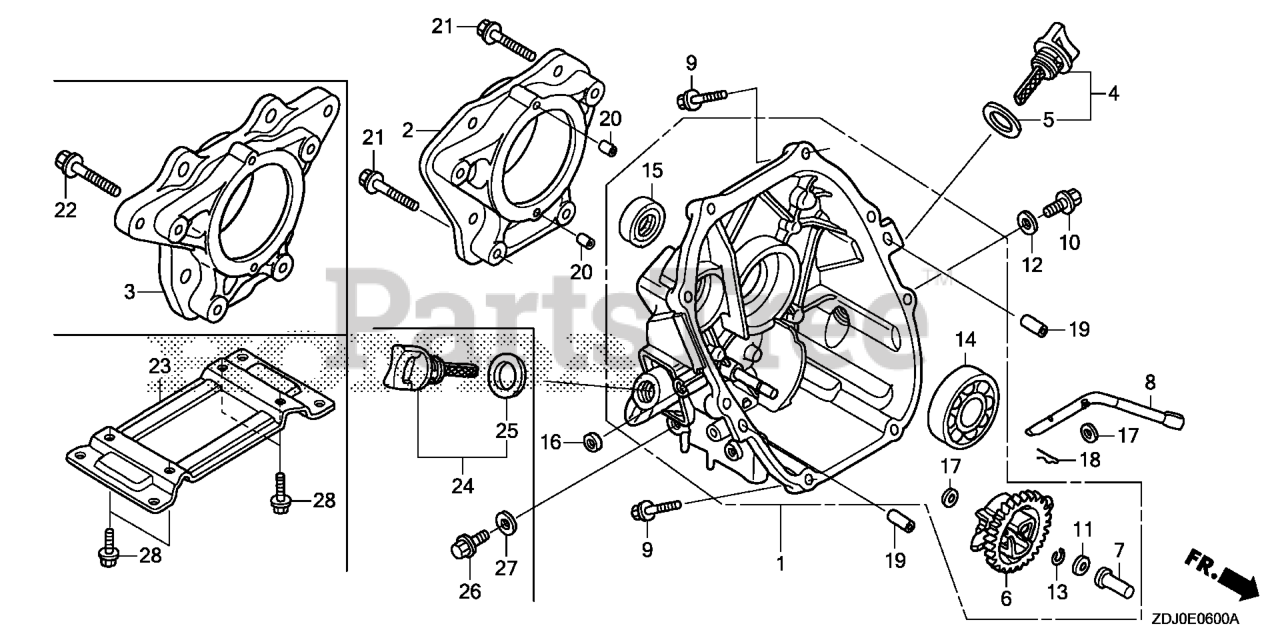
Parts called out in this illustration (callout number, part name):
1	COVER ASSY., CRANKCASE
4	CAP ASSY., OIL FILLER
5	GASKET, OIL FILLER CAP
6	GOVERNOR ASSY.
7	SLIDER, GOVERNOR
8	SHAFT, GOVERNOR ARM
9	BOLT, FLANGE (6X25) Use up to Engine SN 2056819.
10	BOLT, DRAIN PLUG
11	WASHER, THRUST (6MM)
12	WASHER, DRAIN PLUG (10.2MM)
13	CLIP, GOVERNOR HOLDER
14	BEARING, RADIAL BALL (62/22)
15	OIL SEAL (22X41X6)
17	WASHER, PLAIN (6MM)
18	PIN, LOCK (8MM)
19	PIN, DOWEL (8X20)
23	BED, ENGINE
24	CAP ASSY., OIL FILLER
25	GASKET, OIL FILLER CAP
26	BOLT, DRAIN PLUG
27	WASHER, DRAIN PLUG (10.2MM)
28	BOLT, FLANGE (8X25)
